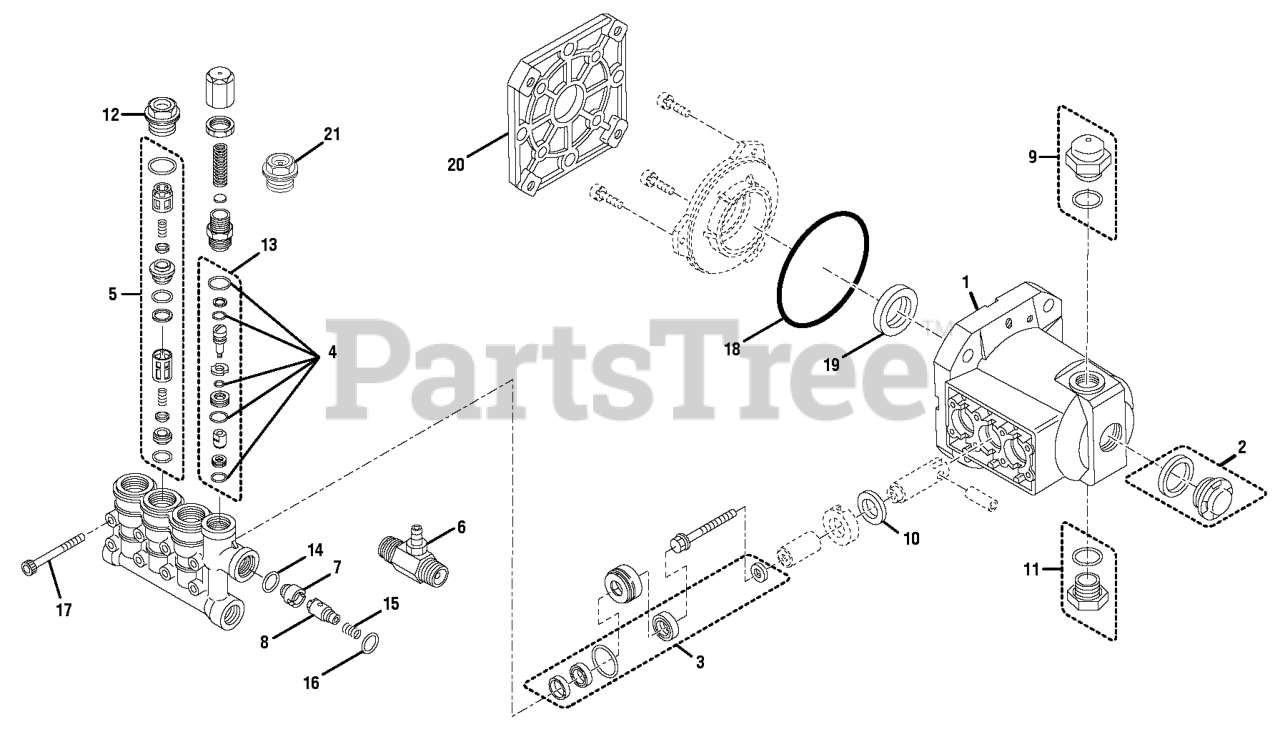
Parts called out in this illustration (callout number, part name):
1	PUMP ASSEMBLY
2	BUBBLE OIL GAUGE W/GASKET
3	SEAL KIT
4	O-RING KIT
5	VALVE KIT
6	CHEMICAL INJECTOR
7	CHECK VALVE SEAT
8	CHECK VALVE W/O-RING
9	VENT CAP (CAT)
10	OIL SEAL
11	DRAIN PLUG
13	UNLOADER ASSEMBLY
17	BOLT
19	OIL SEAL
20	PUMP FLANGE
21	THREADED VALVE PLUG
